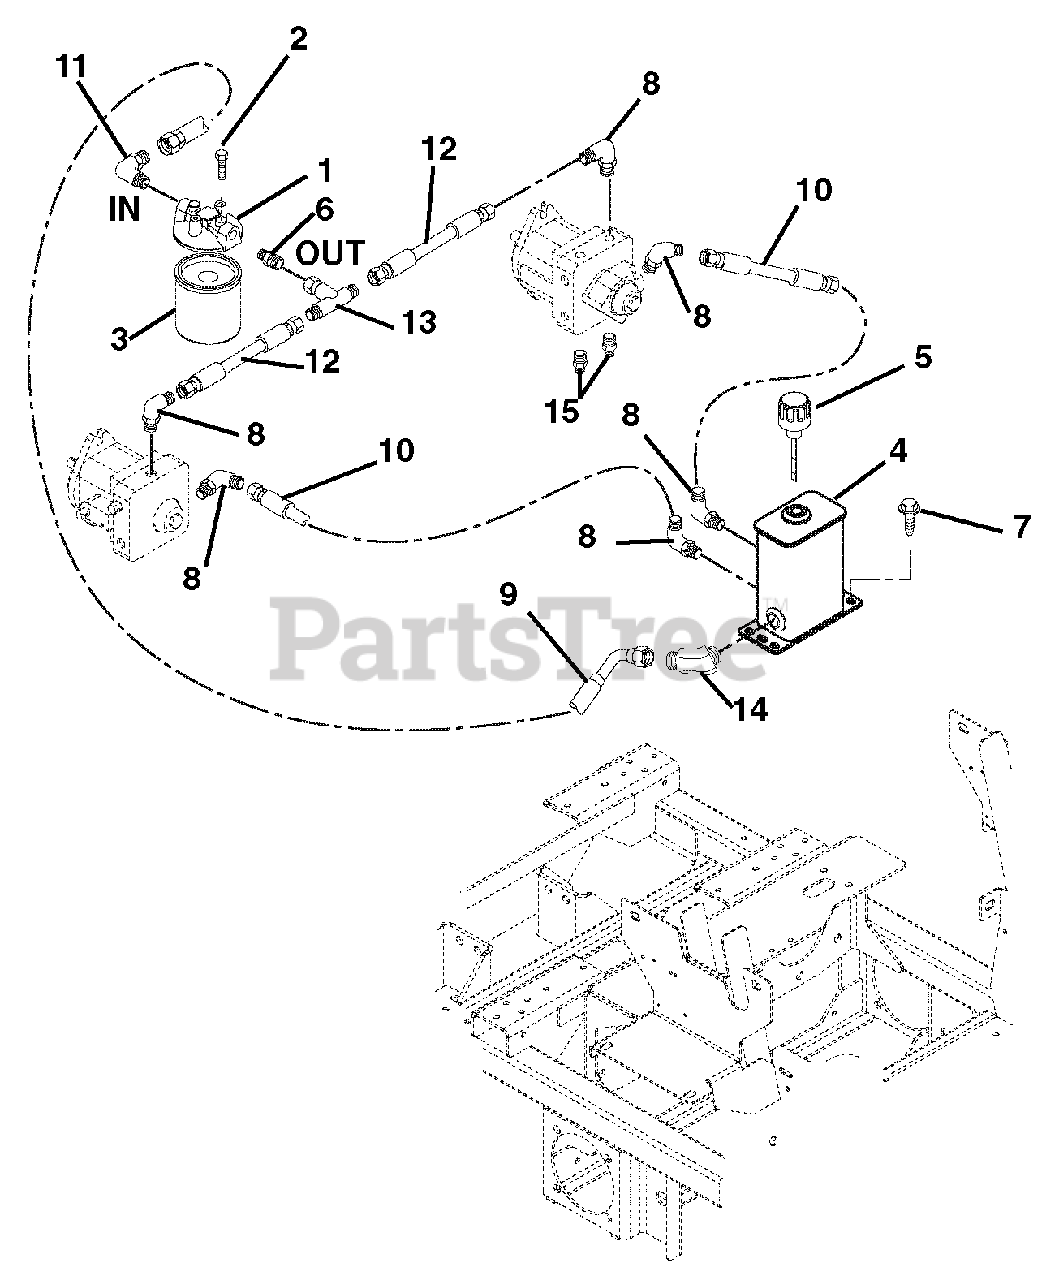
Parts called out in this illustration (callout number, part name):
1	Head, Filter
2	Bolt, Hex .25-20 x .50 Grade 5 Epoxy
3	Filter Element
4	Tank, Hydraulic Formed 3-Port
5	Breather, Dipstick
6	Fitting, Hydraulic, Straight
7	Screw, Tapping .38-16 x .75 Hex Washer Head
8	Fitting, Hydraulic, 90 Degree Elbow
9	Hose, Hydraulic Valve to Tank
10	Hose, Hydraulic, 10-inch
11	Fitting, Hydraulic, 90 Degree Elbow
12	Hose, Hydraulic .50, 5-Inch
13	Fitting, Hydraulic Tee
14	Fitting, Hydraulic 45 Degree
15	Fitting, Hydraulic (4 F5OLO)
